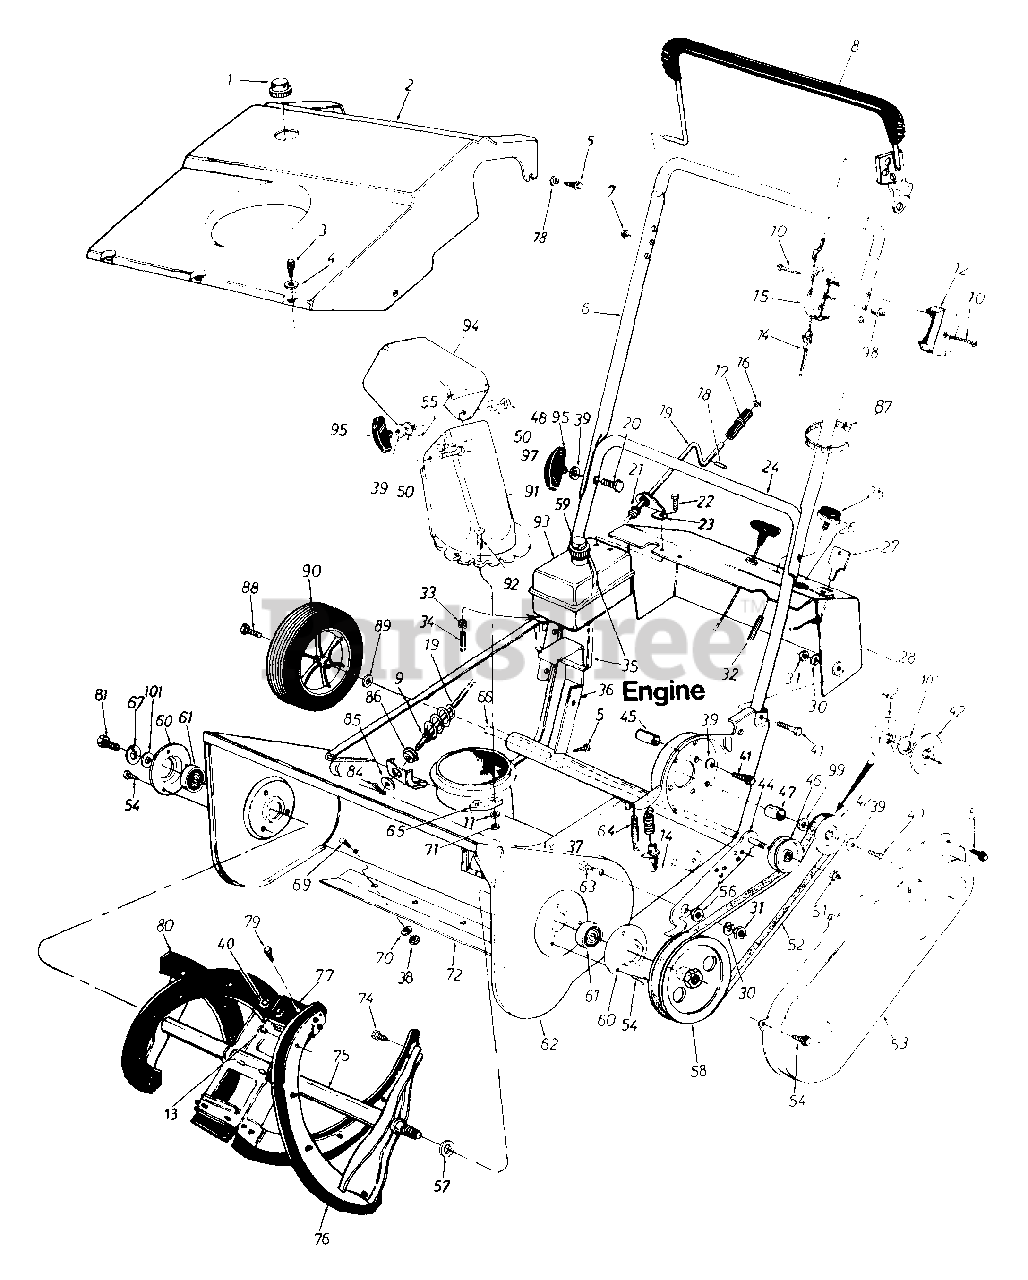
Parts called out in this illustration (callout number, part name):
1	Gas Tank Cap
2	21" Shroud
3	Hex B-Tap Scr. #10 x .38"
4	Spr.-Wash. .206" I.D. x .448"
5	Hex L-Wash. Hd. AB-Tap 1/4 x .62" Lg.
8	Control Handle Ass'y. - L.H.
9	Fl-Wash. .385" I.D. x .62"
10	Truss Mach. Hi-B Tap Scr. #12 x 1.5" Lg.
11	Fl-Wash. .281" I.D. x .5" O.D.
12	Control Panel Half
13	Pop Rivet .187" Dia.
14	Clutch Cable 35" Lg.
15	Control Panel Half
16	Push Cap 3/8" Rod
17	Knob - 3/8" Dia. Hole
18	Roll Pin 1/8" Dia. x .63" Lg.
19	Chute Crank Ass'y.
20	Curved Carriage Bolt 5/16-18 x 1.75" Lg.
21	Chute Crank Grommet
22	Hex AB-Tap Scr. 1/4 x .75" Lg.
23	Upper Chute Crank Brkt.
24	Lower Handle
26	Plastic Plug
27	Plastic Key (Tech. Eng.)
31	Hex Nut 5/16-18 Thd.
32	Primer Hose - 11" Lg.
33	Hose Clamp - 1/2" Dia.
34	Gas Line - 15" Lg.
35	Cable Tie - 17.75" Lg.
39	Bell-Wash. .345" I.D. x .88"
40	Torx AB-Tap Scr. 1/4 x .62" Lg.
41	Hex Bolt 5/16-18 x 1.5" Lg.
42	3/8" "V"-Pulley Half .625" I.D. x 6.0" O.D.
44	Idler Brake Brkt. Ass'y.
45	Spacer .325" I.D. x .625" O.D. x .875"
46	Fl-Idler w/Flanges 2.12" O.D.
47	Spacer .635" I.D. x .89" O.D. x .57"
48	Hex L-Nut 5/16-18 Thd.
49	Hex Bolt 5/16-24 x .75" Lg.
50	Fl-Wash. .344" I.D. x 1.25"
51	Hex Patch L-Nut 3/8-24 Thd.
52	V-Belt
54	Hex B-Tap Ser. 1/4" x .38" Lg.
55	Carriage Bolt 5/16-18 x .75"
56	Shld. Spacer .50" Dia. x .27"
57	Fl-Wash. .510" I.D. x 1.0" O.D.
58	3/8" "V"-Pulley 1/2-20 L.H. x 6"
59	Gas Cap
60	Bearing Cup
61	Ball Brg. .669" I.D. x 1.574"
64	Extension Spring 1.12" Lg.
65	Chute Flange Keeper
66	Wheel Axle 1/2" O.D. x 20.6" Lg.
67	L-Wash. 1/4" I.D.
69	Carriage Bolt 1/4-20 x .50"
70	Fl-Wash. .281" I.D. x .73"
71	Hex L-Nut 1/4-20 Thd.
72	Shave Plate
74	Hex Wash. B-Tap Scr. 1/4 x .62" (Spec )
75	Auger Ass'y. 21"
76	Rubber Spiral - L.H.
77	Rubber Paddle
79	Hex Wash. B-Tap Scr. #10 x .62" Lg.
80	Rubber Spiral - R.H.
81	Hex Wash. TT-Tap Cl-Scr. 1/4-20 x .75" Lg.
84	Cotter Pin 3/32" Dia. x .75"
85	Fl-Wash. .406" I.D. x 1.25"
86	Hex Bushing .385" I.D.
87	Cable Tie
88	Hex Tap Scr. 3/8-24 x .5" Lg.
89	Fl-Wash. .510" I.D. x .75"
90	Wheel & Tire Ass'y. 7" x 1.5"
91	Lower Chute
92	Truss Mach. Scr. 1/4-20 x .75"
93	Fuel Tank - One Qt.
94	Upper Chute
95	Knob Handle Ass'y.
97	Carriage Bolt 5/16-18 x 1"
98	Control Disc Pin
99	Fl-Wash. .635" I.D. x 1.04" O.D.
100	Fl-Wash. .635" I.D. x .93" O.D.
101	Fl-Wash. .25" I.D. x .93"
